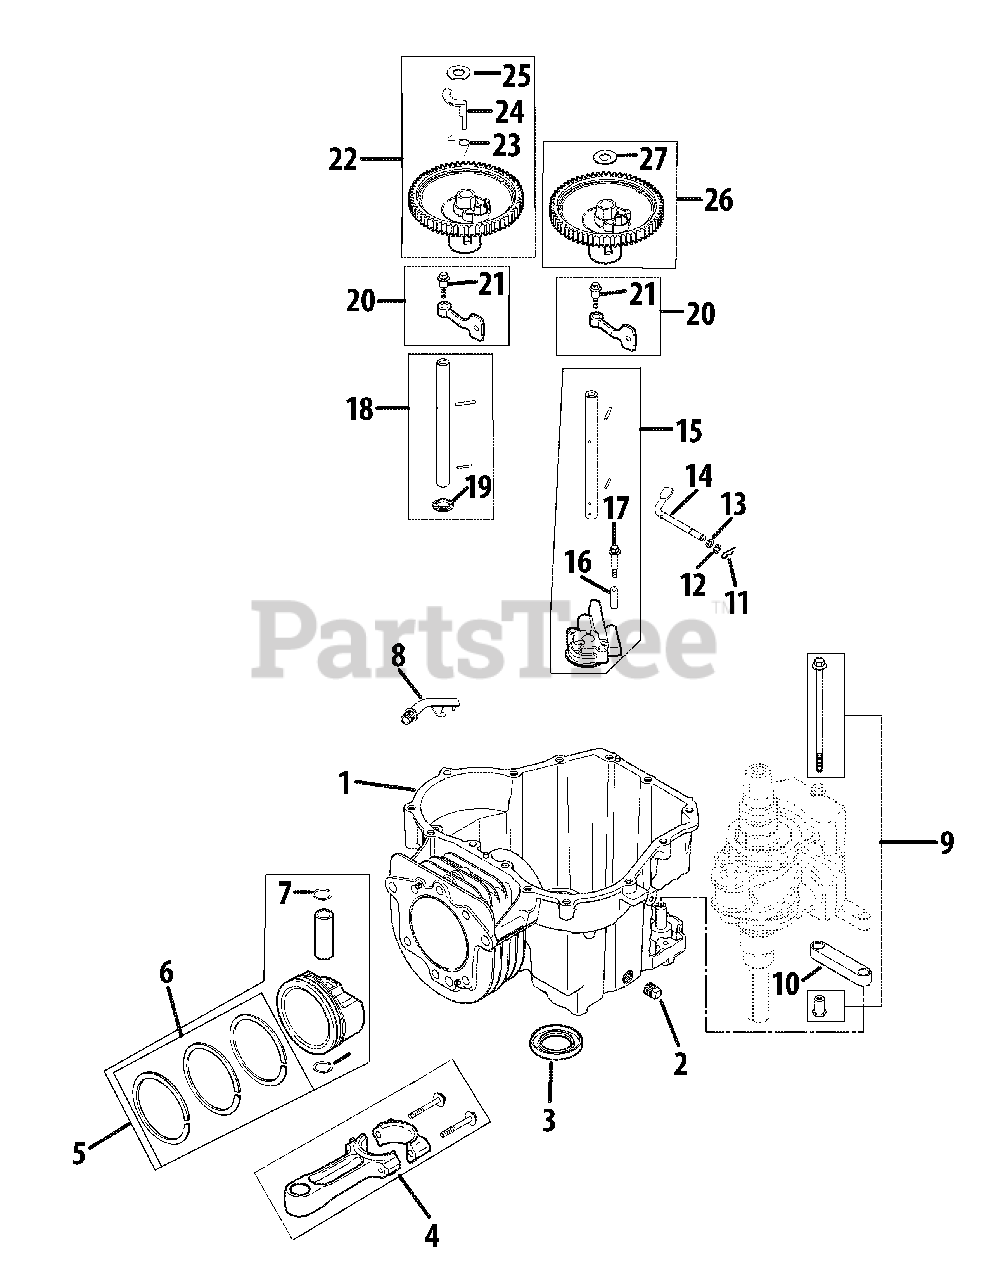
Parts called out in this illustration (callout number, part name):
1	Crankcase
2	Square Head Pipe Plug, 3/8 "
3	Oil Seal
4	Connecting Rod
5	Piston w/ Ring Set Kit
6	Ring Set (94mm)
7	Piston Pin Retainer
8	Drainback Tube
9	Locating Pin Kit
10	Balance Weight Linkage
11	Hitch Pin Clip
12	Flat Washer 6mm
13	Flat Washer, 1/4"
14	Governor Cross Shaft
15	Oil Pump Assembly Kit
16	Oil Pump Screw Spacer
17	Oil pump Screw
18	Cam Center Shaft Kit
19	Thrust Washer
20	Cam Lever Assembly Kit
21	Shd Thd Frm Screw, M6 x 1 x 26
22	Camshaft Assembly Kit
24	ACR Weight
25	ACR Thrust Washer
26	Camshaft Assembly Kit
27	ACR Thrust Washer
